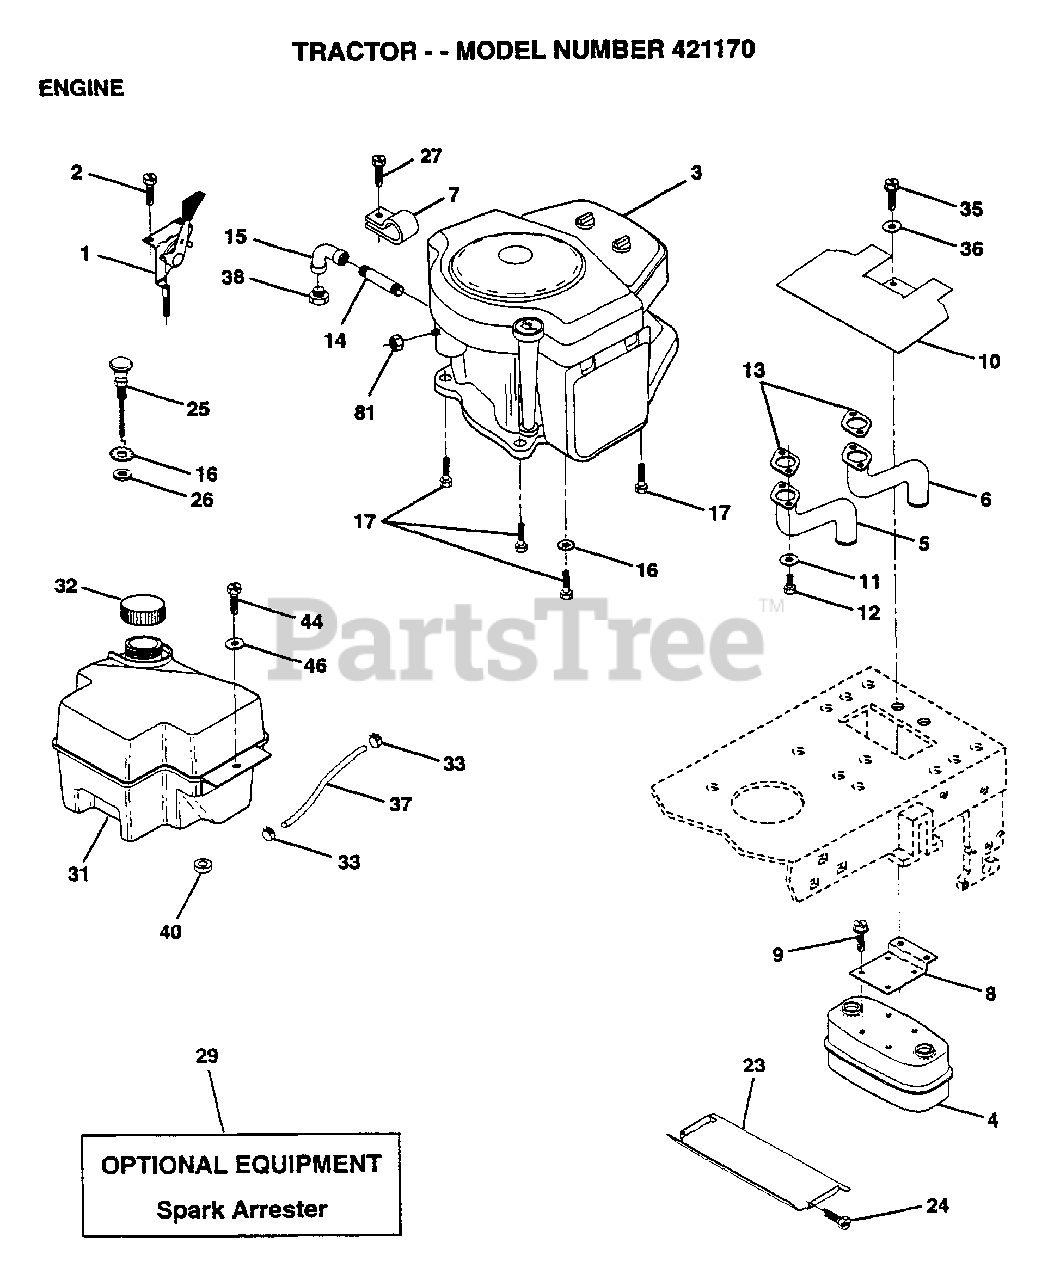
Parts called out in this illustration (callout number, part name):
1	CONTROL THRT 35.5
2	SCREW LT
5	EXHAUST.B&S.18.LH
6	EXHAUST.B&S.18.RH
7	CLAMP.TUBE.DBL.EN
8	BRACKET MUFFLER
9	SCREW ST
10	SHIELD.HEAT.
14	PIPE NIPPLE LT
15	ELBOW
16	LOCKWASHER
17	SCREW LT
23	HEAT SHIELD
24	SCREW
25	CONTROL.CHOKE.37
27	SCREW.10-24X1/2
32	CAP ASM FUEL
33	HOSE CLAMP
35	SCREW
36	WASHER
37	LINE FUEL
44	SCREW HEX CRT
46	WASHER
81	NUT
